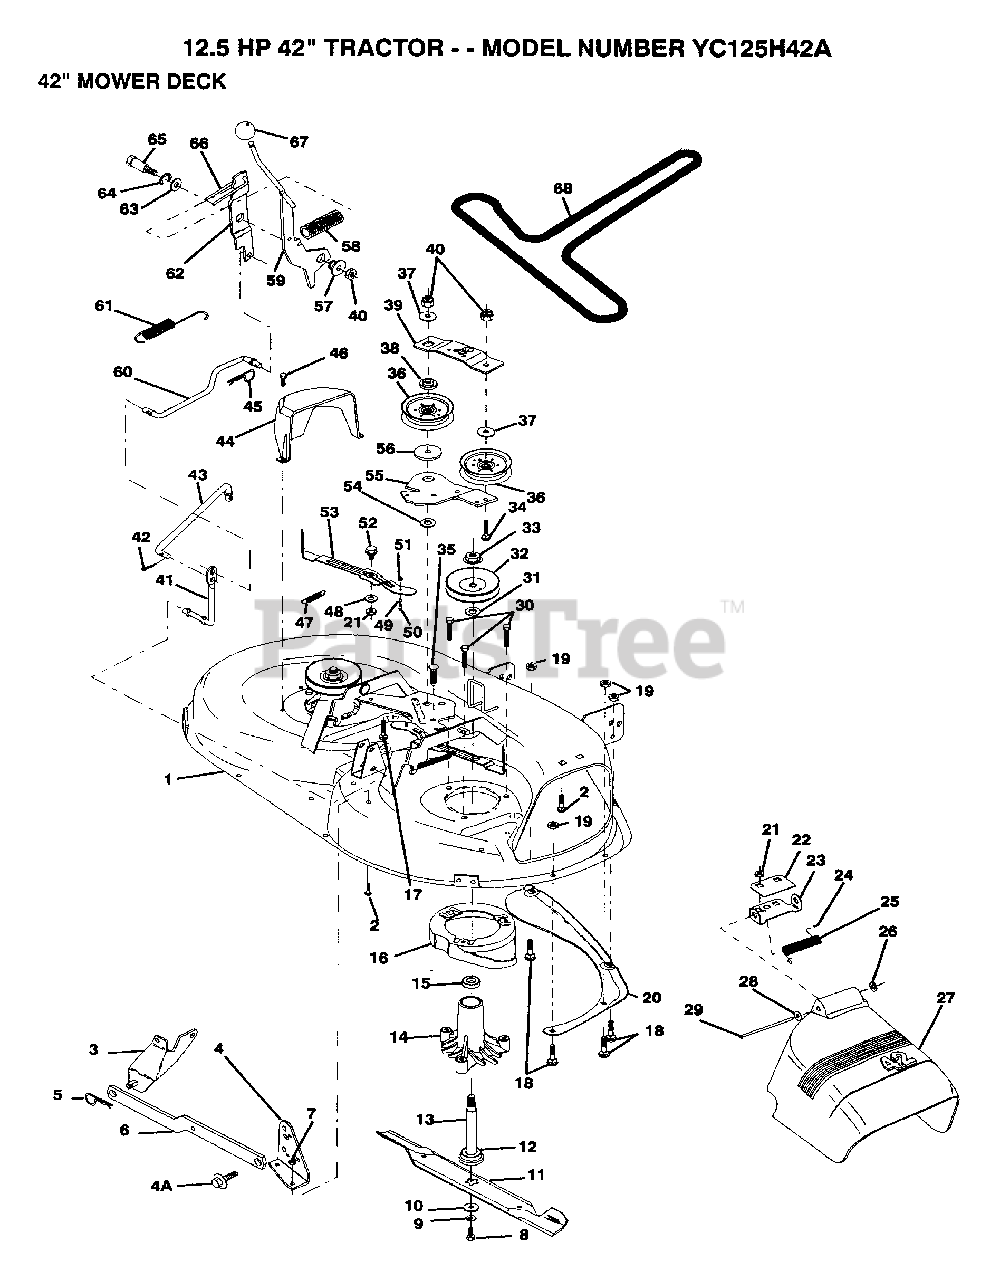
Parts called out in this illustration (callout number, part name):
2	BOLT
3	BRKT ASM SWAY BAR
4	BRKT DECK SW BAR
4A	BOLT SHD 5/16-18
7	NUT
8	BLADE BOLT
10	WASHER BLADE
11	"BLADE.42"" HIPERF"
12	BEARING.BALL
14	HSG ASM MANDREL
15	BEARING
17	BOLT CARRIAGE
18	BOLT
19	NUT
22	STIFFENER BRKT
23	DEFLECTOR BRKT
24	CAP-SLEEVE LT
25	SPRING TORSION
26	NUT PUSH M
27	DEFLECTOR.SHIELD
28	WASHER
29	HINGE ROD
31	WASHER
34	BOLT
35	XMAS TREE FASTNER
36	FLAT IDLER PULLEY
37	WASHER GT
38	RETAINER SPACER
39	IDLER ARM STIFF
41	PIVOT ROD
43	CLUTCH ROD SECOND
45	RETAINER M
46	SCREW.1/4-20X5/8
47	SPRING EXTENSION
48	HARD SMALL WASHER
50	SHOULDER BOLT
51	LOCKNUT
53	BRAKE PAD ARM ASM
54	HARDENED WASHER
55	IDLER ARM
56	SPACER RETAINER
57	BUSHING
59	CLUTCH ARM PRI AS
60	"ROD, CLUTCH PRIM"
61	RETURN SPRING
62	CLUTCH ARM SECOND
63	WASHER
64	RING
65	SHOULDER BOLT
66	SPRING KEEPER
67	KNOB T(3/8 HOLE)
68	BELT-V.92.4.MWR
